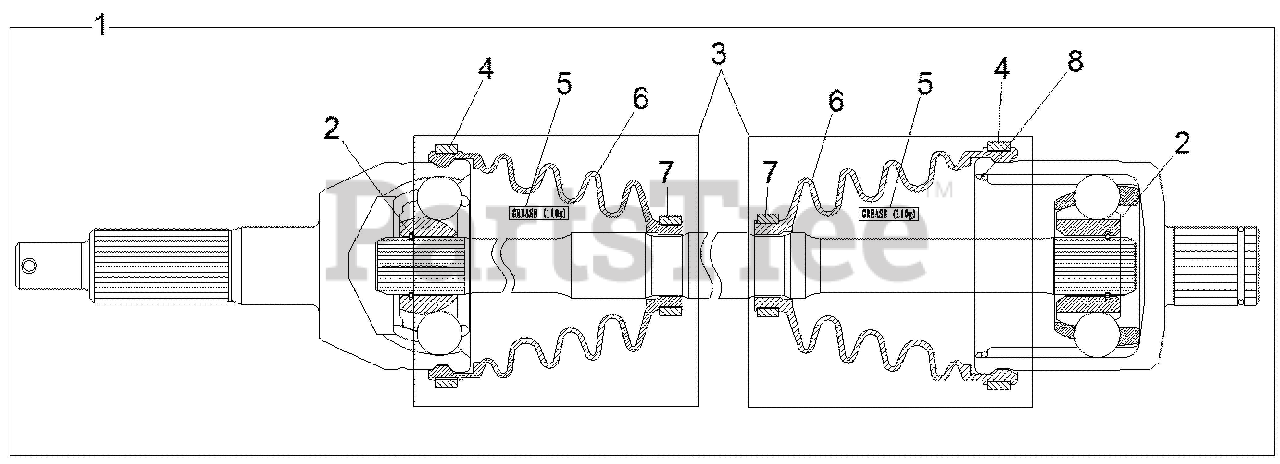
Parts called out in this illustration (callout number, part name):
1	ASM-DRIVESHAFT,REAR
2	CIRCLIP(PR-3041)
3	KIT-BOOT(PR-8071)
4	CLAMP-LARGE(PR-0027)
5	GREASE(K575/VW738)
6	BOOT(PR-0025)
7	CLAMP-SMALL(PR-0026)
8	RING-RUBBER(JIB)
